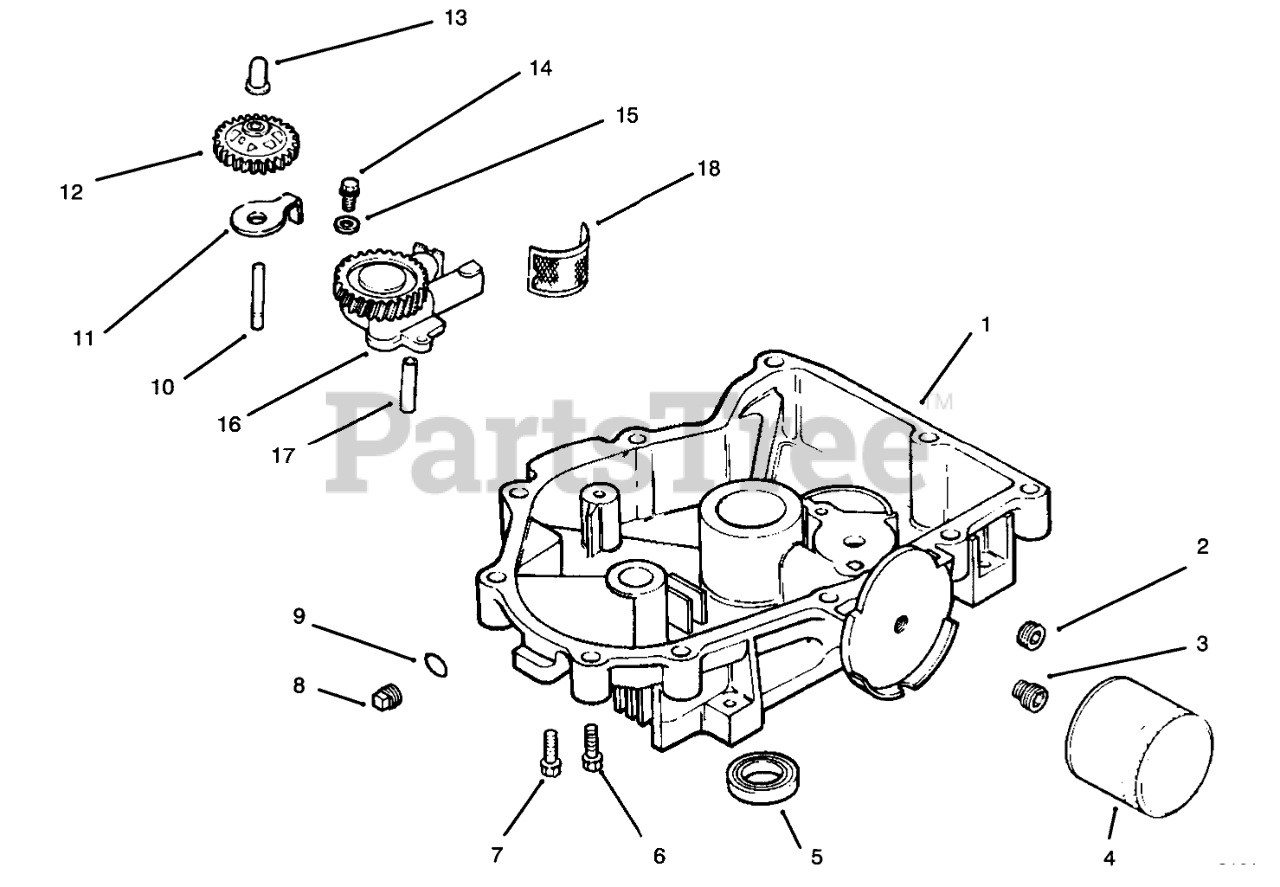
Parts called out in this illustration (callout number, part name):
1	Pan-Oil
3	Nipple-Oil Filter
4	Filter-Oil
5	Seal-Oil
6	Screw
7	Screw
10	Shaft-Govenor Gear
11	Tab-Locking
12	Kit-Governor Gear (Incl. Ref. #13)
13	Pin-Governor Regulating
16	Oil Pump Assembly (Incl. Ref. #17)
17	Tube-Oil Pickup
18	Screen-Oil
